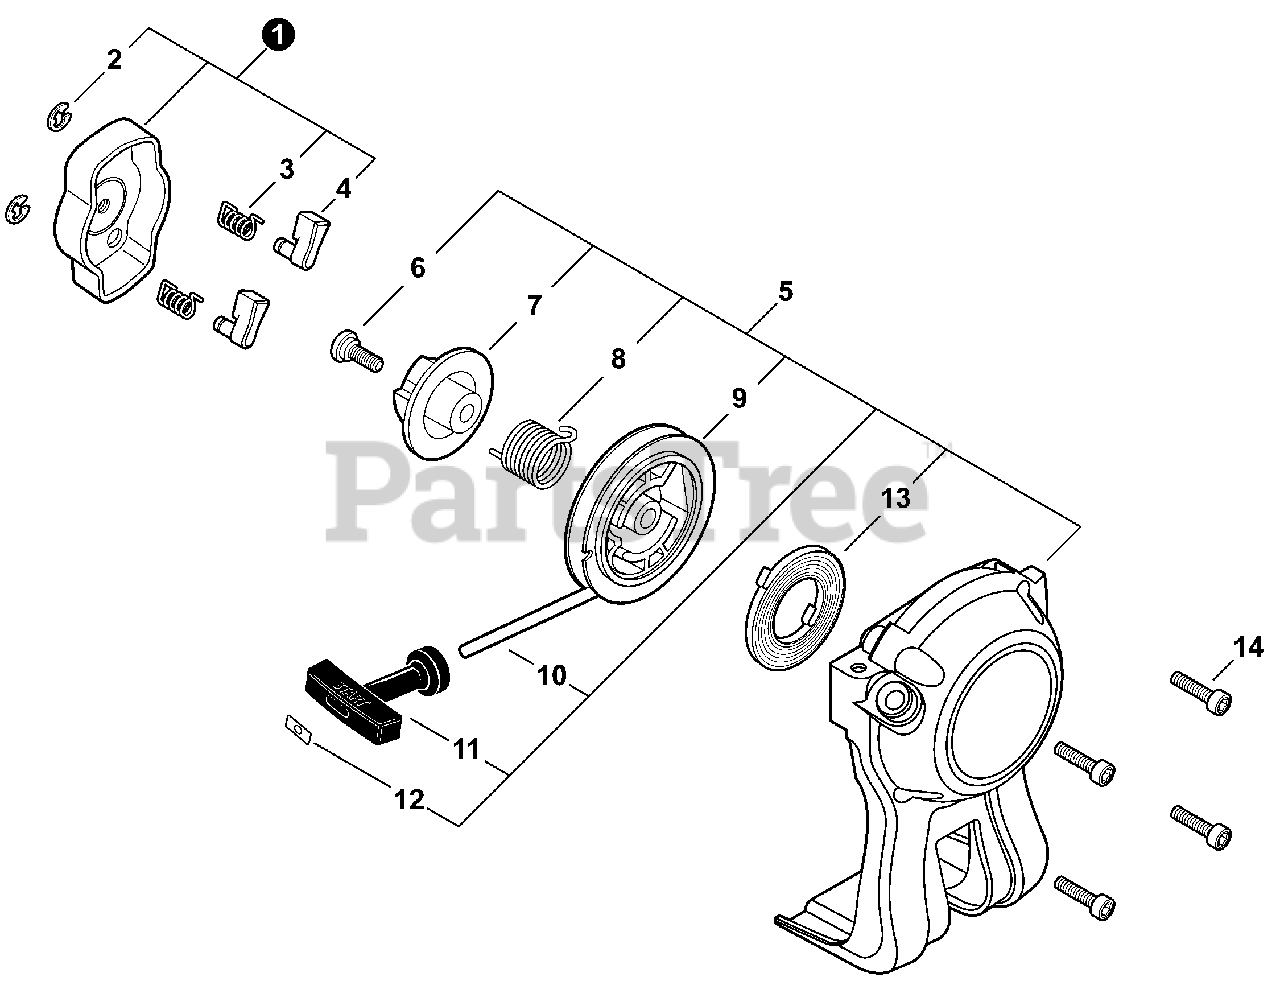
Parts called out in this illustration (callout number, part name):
1	PAWL ASSY, STARTER
2	E-RING 4
3	SPRING, RETURN
4	PAWL, STARTER
5	STARTER ASSY, RECOIL
6	SCREW
7	PLATE, CAM
8	SPRING, TORSION
9	REEL, ROPE
10	ROPE, STARTER
11	GRIP, STARTER
12	RETAINER, ROPE
13	SPRING, RECOIL
14	BOLT, TORX 4×16
